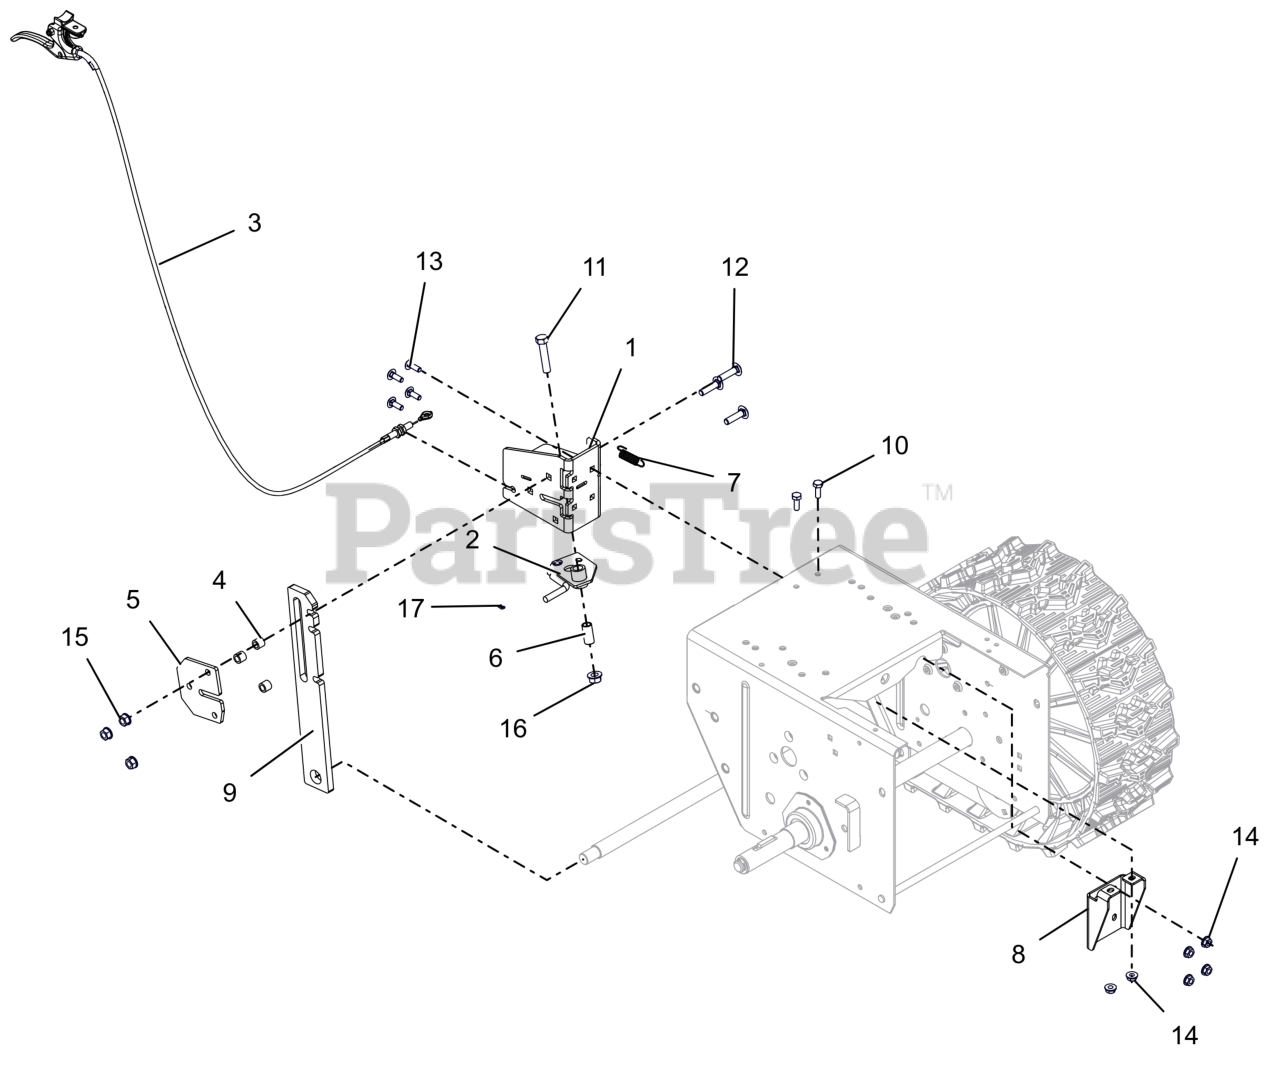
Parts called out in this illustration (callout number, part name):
1	BRACKET,HEIGHT ADJUSTER-DELUXE
2	LOCK,HEIGHT ADJUSTER TRIGGER
3	CABLE, TRACK REMOTE
4	SPACER .50 X .32 X .42
5	PLATE, HEIGHT ADJUSTER
6	BSHG-SLV .385X.500X1.045
7	SPRING-EXT .047 X .438 X 1.85
8	BRACKET, REINFORCEMENT
9	ADJUSTER, HEIGHT-BWT
10	BLT, HEX .25-20X.75 G5 ZCC
11	BLT, HEX .38-16X1.75 G5 ZCC
12	BLT, RHSSN.31-18X1.25 G5 ZCC
13	BLT, RHSN .25-20X.750 G5 ZCC
14	NUT-LK-CTR-FLG .25-20 ZC120
15	NUT-LK-TOP-FLG .312-18 GF ZCC
16	NUT-LK-CTR-FLG .375-16 GF ZCC
17	PIN, HAIR #178 .06X.77 ZCC
